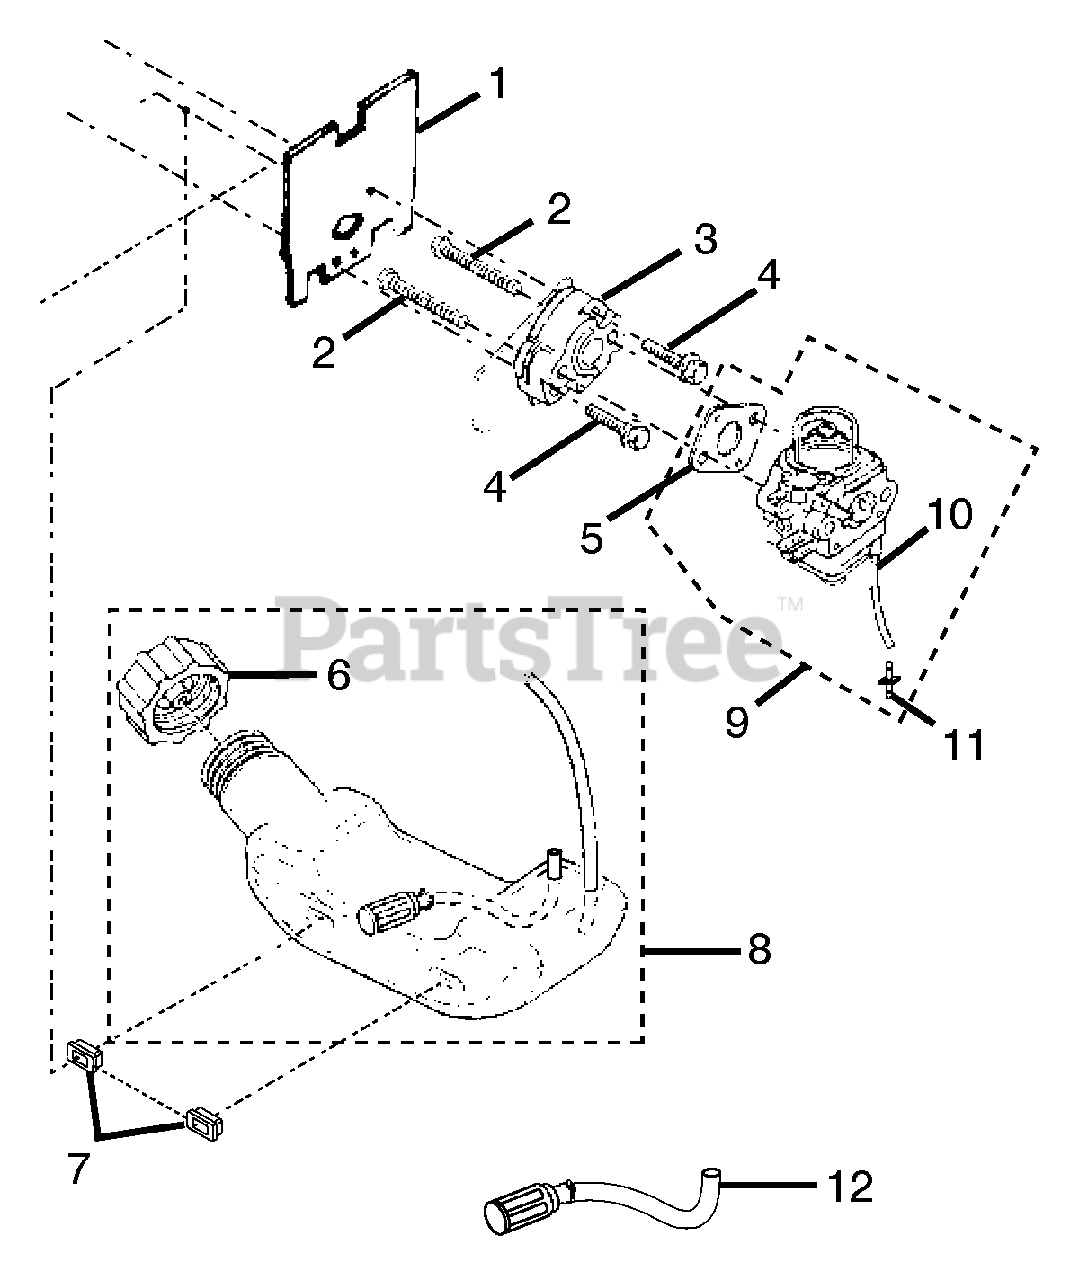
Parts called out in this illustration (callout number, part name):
1	HEAT DAM GASKET
2	CARBURETOR BOLT
3	HEAT DAM
4	PAN HEAD SEMS SCREW
5	CARBURETOR GASKET
6	FUEL CAP
8	FUEL TANK ASSEMBLY
9	CARBURETOR ASSEMBLY KIT
10	RUBBER HOSE (635 mm)
11	INLINE FUEL FITTING
12	FUEL FILTER KIT
